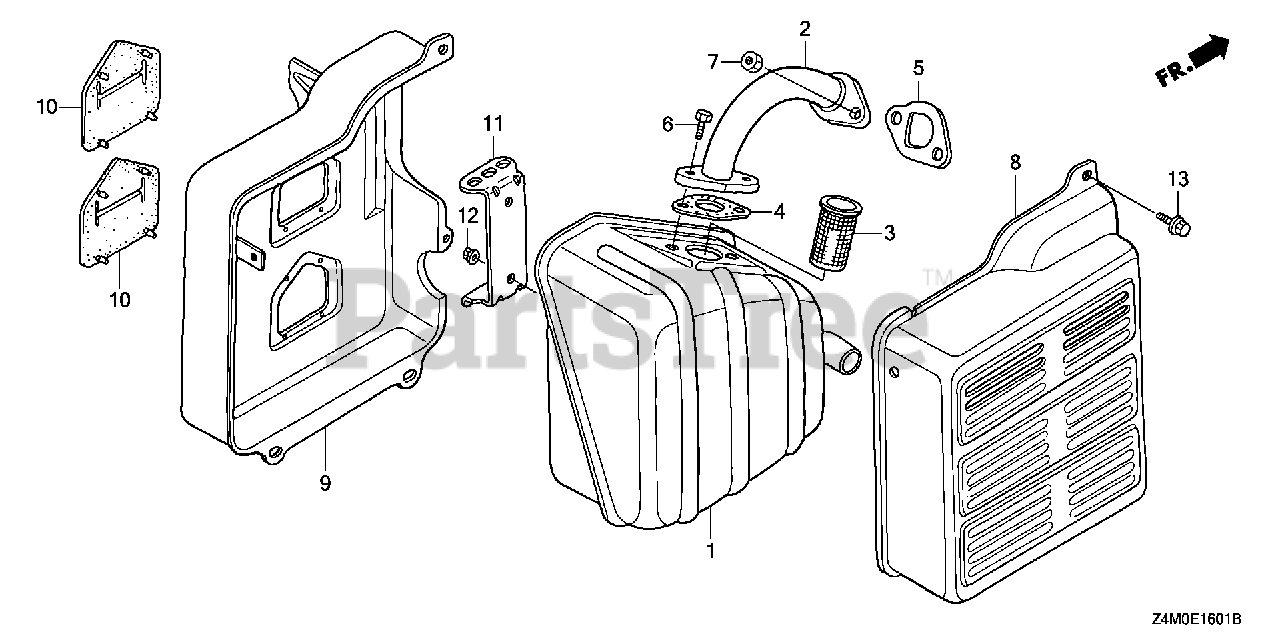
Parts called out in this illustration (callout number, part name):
1	MUFFLER
3	ARRESTER, SPARK
4	GASKET, MUFFLER
5	GASKET, MUFFLER
8	PROTECTOR, MUFFLER (OUTER)
9	PROTECTOR, MUFFLER (INNER)
10	SEAL, MUFFLER PROTECTOR
11	STAY, MUFFLER
12	NUT, FLANGE (6MM)
13	BOLT, FLANGE (6X12) Use up to Engine SN 1543277.
